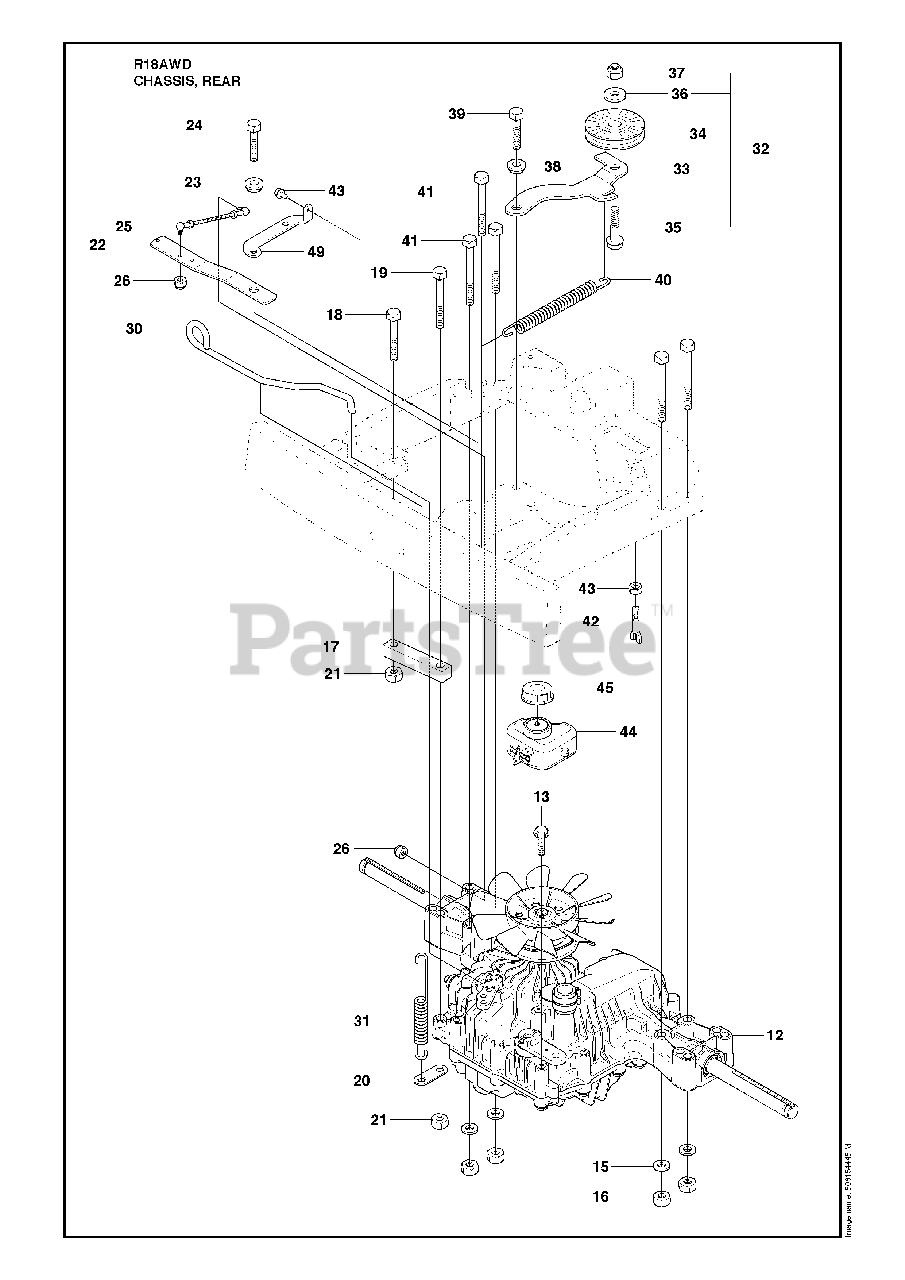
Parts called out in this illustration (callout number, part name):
2	Ball Bearing
3	BALL BEARING 6010 2RS1
4	CIRCLIP SGH 47
5	RETAINING RING SGA 25
7	RETAINING RING SGA 25
12	HYDRAULMOTOR
15	WASHER BRB 8.4X17
16	NUT
21	NUT
23	WASHER
24	SCREW 8X20
26	LOCKNUT M5
33	TENSIONER
35	SCREW
37	LOCKNUT M8
38	WASHER
39	SCREW 8X20
43	NUT
47	REPL BY 725 25 00-71
48	COUNTERWEIGHT
